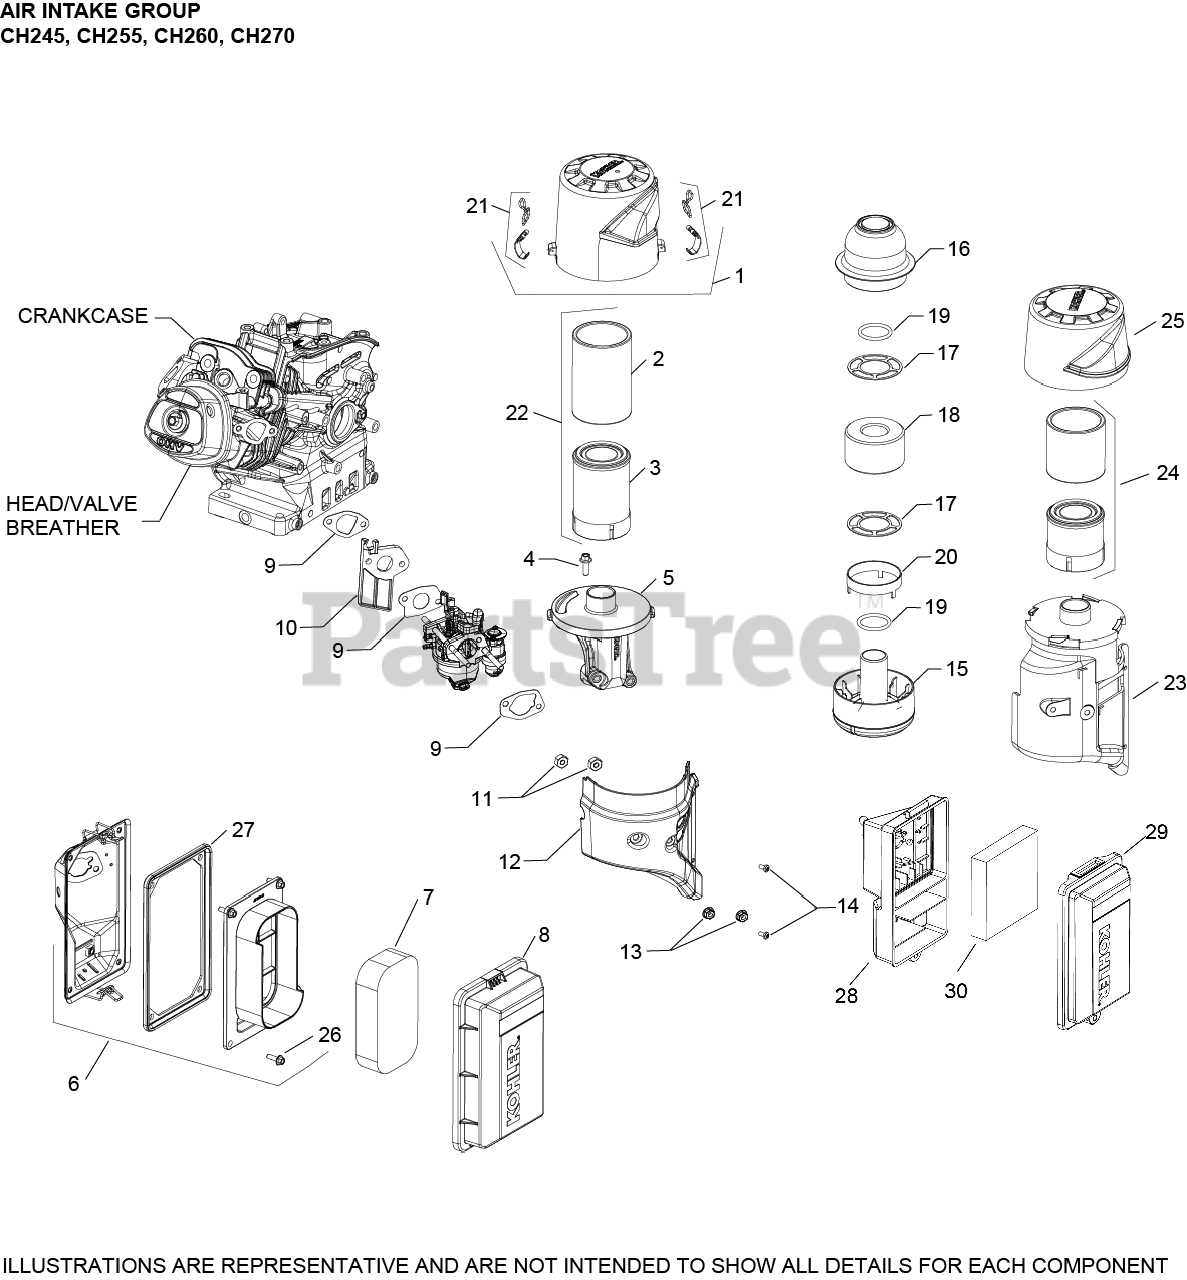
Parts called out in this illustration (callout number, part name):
1	COVER, AIR CLEANER ASSEMBLY
2	ELEMENT, PRE-CLEANER - USE 17 083 12-S
3	ELEMENT, AIR FILTER USE 17 083 23-S
4	SCREW, M6 X18
5	KIT, AIR CLEANER BASE ASSEMBLY
10	SCREW,COVR TO BLWR HOUSING
11	NUT, HEX (M6 THREAD, M8 BODY)
12	COVER, AIR CLEANER BASE SHIELD
13	NUT, HEX FLANGE LOCK (M6)
14	SCREW,COVR TO BLWR HOUSING
21	KIT, LATCH CLIP
